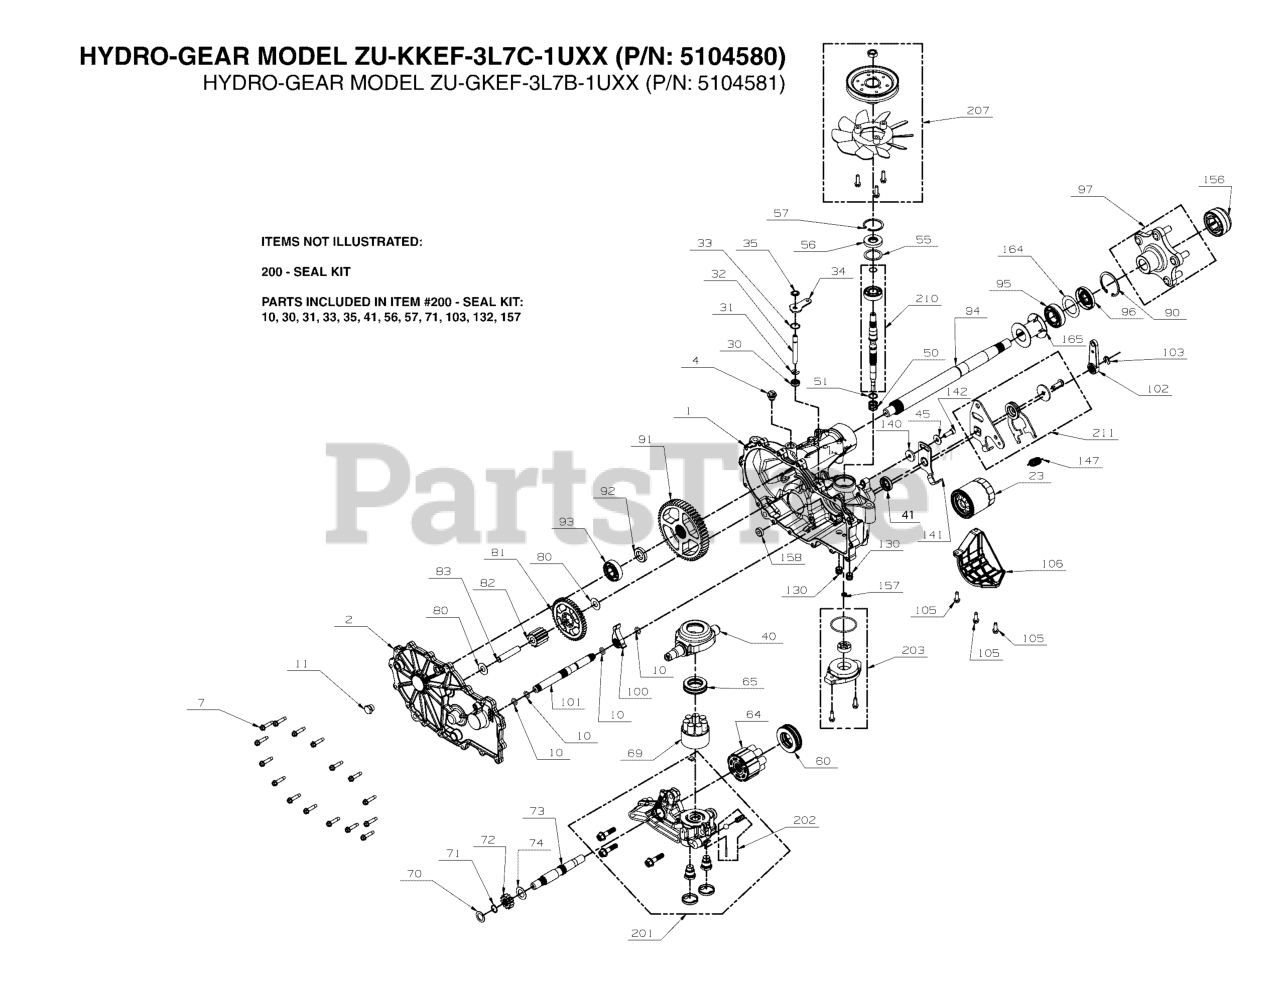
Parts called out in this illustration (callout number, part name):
23	FILTER, OIL, ZT2800
30	SEAL, .375 X .750 X .25 LIP, H/G 51626
41	SEAL, CONTROL ARM, 18X32X7, #51140
56	OUTPUT SHAFT SEAL, 17X40X7, HR #51161
96	KIT, SEAL, AXLE - HG# 53699
200	KIT, SEAL - HG# 73239
207	FAN & PULLEY KIT, ZT3400'S, STAND-ON
210	KIT, INPUT SHAFT (BEARING AND SHAFT ONLY)
1000	KIT, PLUG, BRAKE BORE, OUTBOARD
